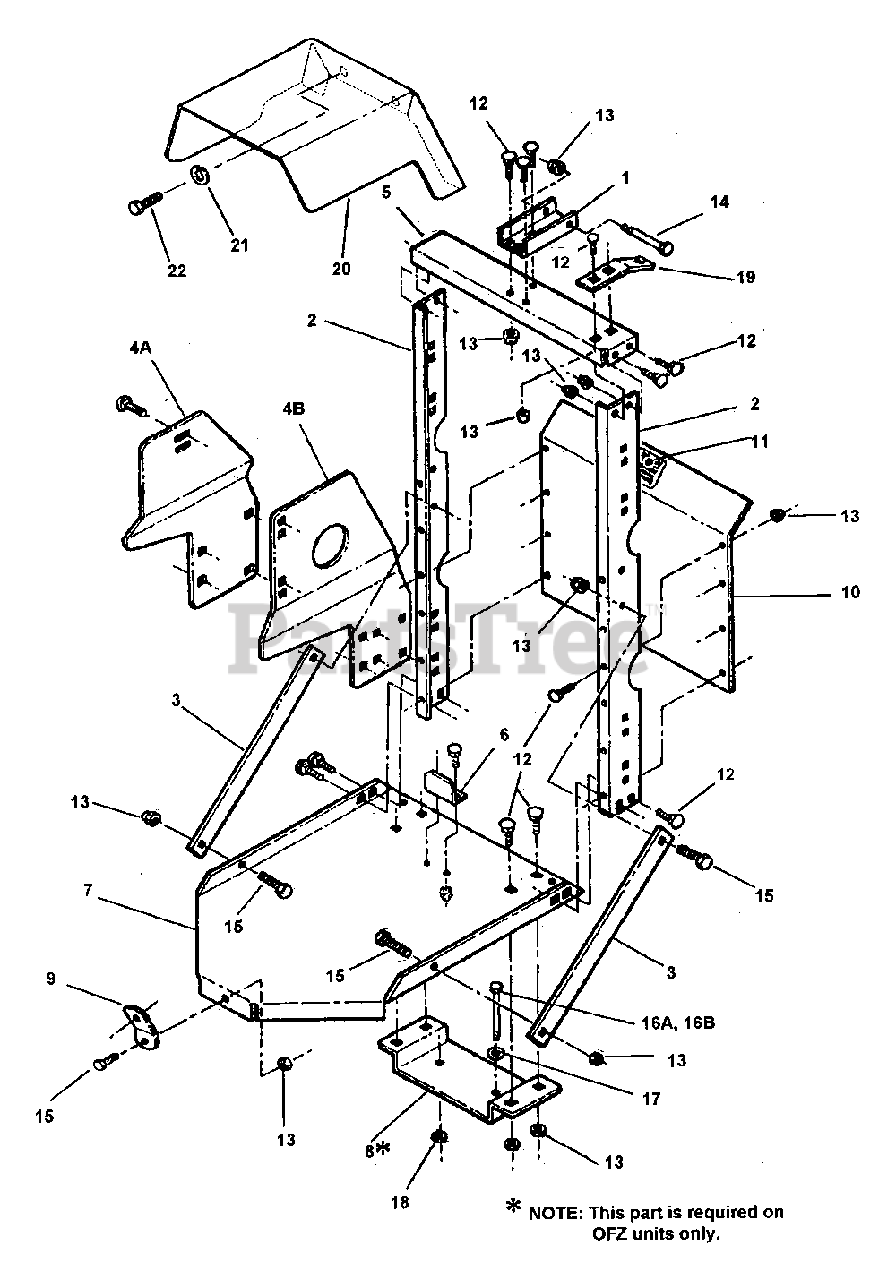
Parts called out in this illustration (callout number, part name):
1	BRACKET, Lower Hinge
2	ANGLE, Upright
3	STRAP, Plate Support
4A	BRACE, Left Hand Grass Catcher (MMZ)
4B	BRACE, Left Hand Grass Catcher (OFZ)
5	CHANNEL, Cross Brace
6	BRACKET, Stop
7	Plate, Cannister
9	PLATE, Retainer
10	ASSEMBLY, Heat Shield & Decal
11	DECAL, Heat Shield
12	BOLT, 5/16-18 x 3/4" Short Neck Carriage, Grade 5
13	NUT, 5/16-18 HEX NYLON LOCK
14	BOLT, 5/16-18 x 4-1/2" Hex Head, Grade 2
15	BOLT, 5/16-18 X 1 GD5 YZ
16A	SCREW, 3/8-16 x 5-1/4" Hex Head Cap, Gr. 5 (Kohler OFZ Models)
16B	SCREW, 3/8-16 x 1-1/2" Hex Head Cap, Gr. 5 (Kubota OFZ Models)
17	WASHER, 3/8" Flat
18	NUT, 3/8-16 HEX NYLON LOCK
19	BRACKET, Chute Hanger
20	SHIELD, PTO Clutch (Kubota Models Only)
21	WASHER, .32 Split Lock
22	BOLT, M8-1.25 X 25MM GD8.8
